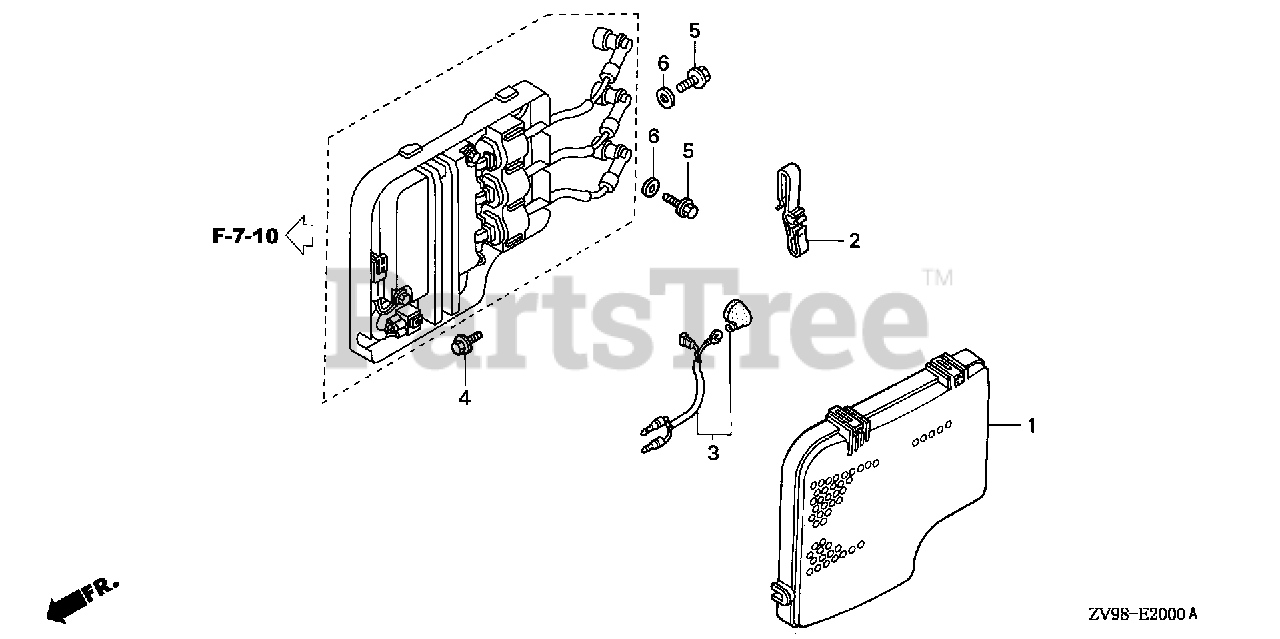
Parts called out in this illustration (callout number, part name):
1	COVER, IGNITION CONTROL MODULE (CDI)
2	CLAMP, CENTER WIRE
3	WIRE, SWITCH (385MM)
4	BOLT, FLANGE (6X12)
4	BOLT, FLANGE (6X12) (CT200)
5	BOLT, FLANGE (6X25)
6	WASHER, PLAIN (6MM)
